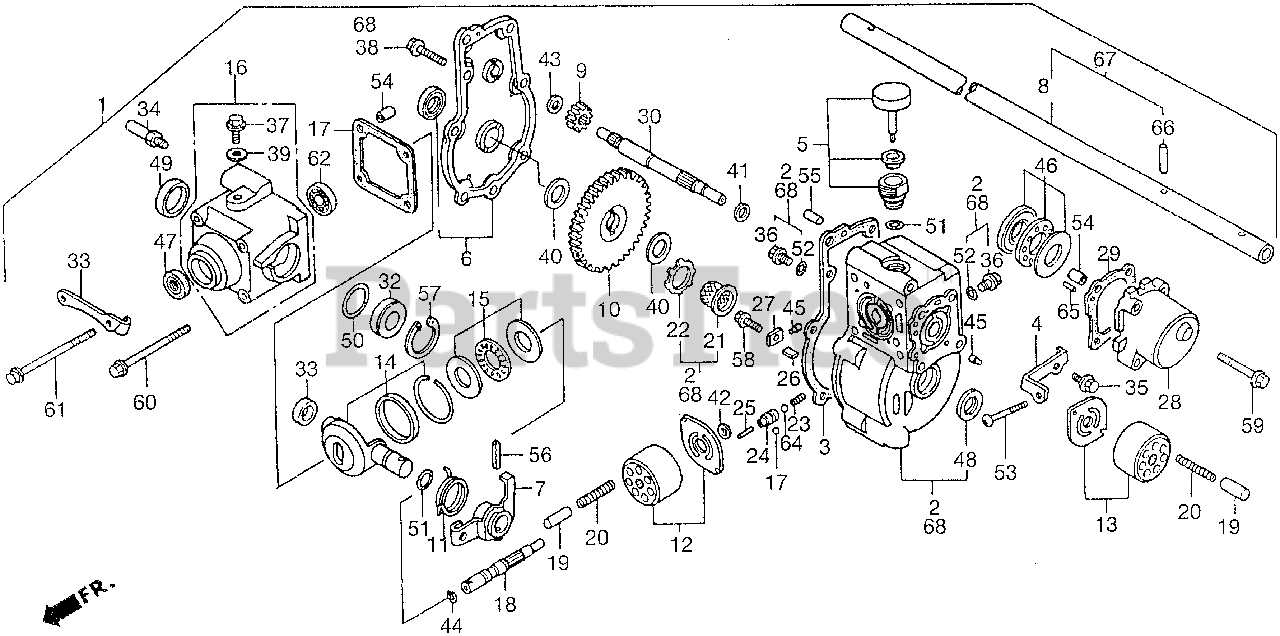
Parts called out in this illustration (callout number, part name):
1	TRANSMISSION ASSY.
2	CASE, TRANSMISSION
3	GASKET, TRANSMISSION CASE
4	BRACKET, CONTROL ARM ADJUSTING
6	COVER, TRANSMISSION
7	ARM, CONTROL
8	SHAFT, FINAL (NOT AVAILABLE)
9	GEAR, FINAL DRIVE (12T)
10	GEAR, FINAL DRIVEN (66T)
11	SPRING, CONTROL ARM RETURN
12	PLATE SET, PUMP CYLINDER
13	PLATE SET, MOTOR CYLINDER
14	BOWL SET, CONTROL
15	BEARING SET, THRUST NEEDLE
16	CASE SET, PUMP
17	GASKET, PUMP CASE
18	SHAFT, PUMP
19	PISTON, PUMP
20	SPRING, PISTON
21	FILTER, SUCTION
22	PLATE, FILTER
23	SPRING, RELIEF VALVE
24	BODY, NEUTRAL VALVE
25	NEEDLE A, NEUTRAL VALVE (22.4)
25	NEEDLE B, NEUTRAL VALVE (22.6)
25	NEEDLE C, NEUTRAL VALVE (22.8)
25	NEEDLE D, NEUTRAL VALVE (23.0)
25	NEEDLE E, NEUTRAL VALVE (23.2)
27	PLATE, MAGNET SETTING
28	CASE, MOTOR
29	GASKET, MOTOR CASE
30	SHAFT, MOTOR
31	BUSH, CONTROL BOWL (A)
32	BUSH, CONTROL BOWL (B)
33	HOLDER, CONTROL CABLE
34	BOLT, GUIDE (8MM)
35	BOLT, FLANGE (5X10)
36	BOLT A, PLUG (NOT AVAILABLE)
37	BOLT, SEALING (8MM)
38	BOLT, FLANGE (6X21)
39	WASHER, SEALING (8X16X1.6)
40	WASHER (15X24X3.2)
41	WASHER, THRUST (10X16X1)
42	WASHER, THRUST (13X8.3X1.6)
43	WASHER, THRUST (8.6X13X0.6)
44	CLIP B, BEARING
45	PIN, DOWEL (3X5.8)
46	BEARING, THRUST BALL
47	OIL SEAL (10X20X5)
48	OIL SEAL (15X24X5)
49	PLUG, SEAL (22X7)
50	O-RING (25X2.4)
51	O-RING (11.8X1.9)
52	O-RING (6.8X1.9)
53	SCREW, PAN (5X30)
54	PIN, DOWEL (8X10)
55	PIN C, DOWEL (4X6.5)
56	PIN, SPRING (5X20)
57	CIRCLIP (INNER) (30MM)
58	BOLT, FLANGE (6X12)
59	BOLT, FLANGE (6X32)
60	BOLT, FLANGE (6X60)
61	BOLT, FLANGE (6X65)
62	BEARING, RADIAL BALL (6000)
63	BALL, STEEL (#5) (5/32)
64	BALL, STEEL (#8) (1/4)
65	ROLLER (4X19.8)
66	ROLLER (6X22.4)
67	SHAFT, FINAL
68	CASE SET, TRANSMISSION
